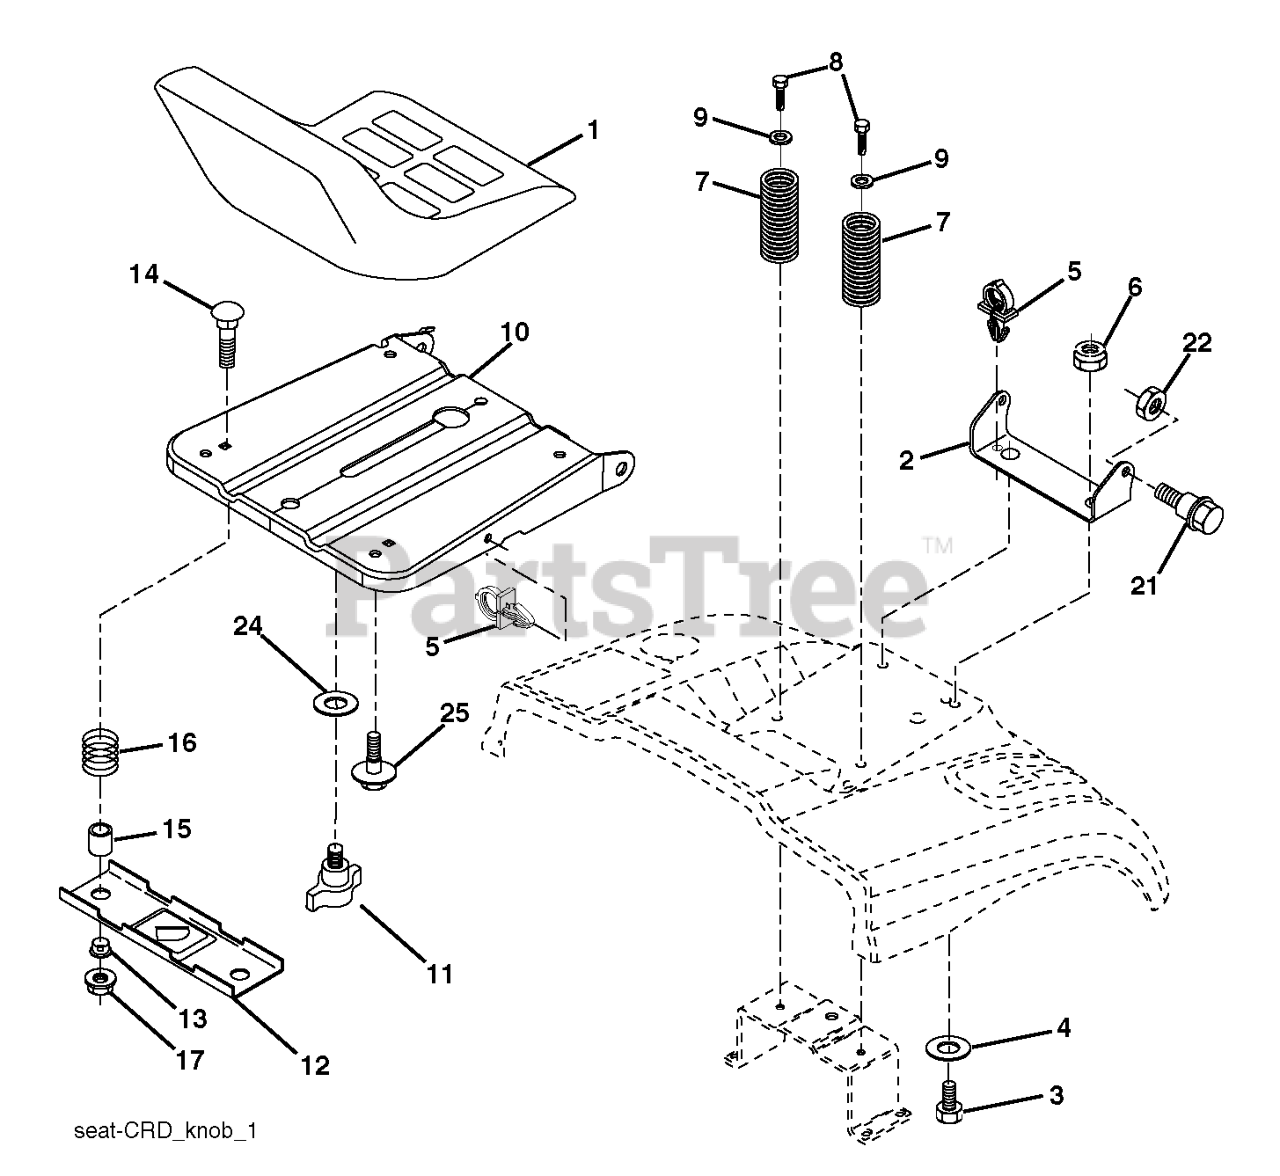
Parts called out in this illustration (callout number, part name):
1	RP SEAT
2	SEAT PIVOT BRKT
3	BOLT, HEX 3/8-16X1
6	NUT
7	SPRING COMPRESSION
8	SCREW 3/8-16X1
9	WASHER
10	PAN.ASM.SEAT.1SLOT
11	KNOB.SEAT.ADJ.WINGNUT
12	BRKT.MNTNG.SWITCH.SEAT.BLACK
14	BOLT.ROUND.HEAD.SQUARE.NECK
15	SPACER SPLIT 28X.96
17	NUT T
21	BOLT.SHOULDER.5/16-18
22	NUT.71038.31-18.HEX.NYLOCK
25	BOLT,SHOULD
